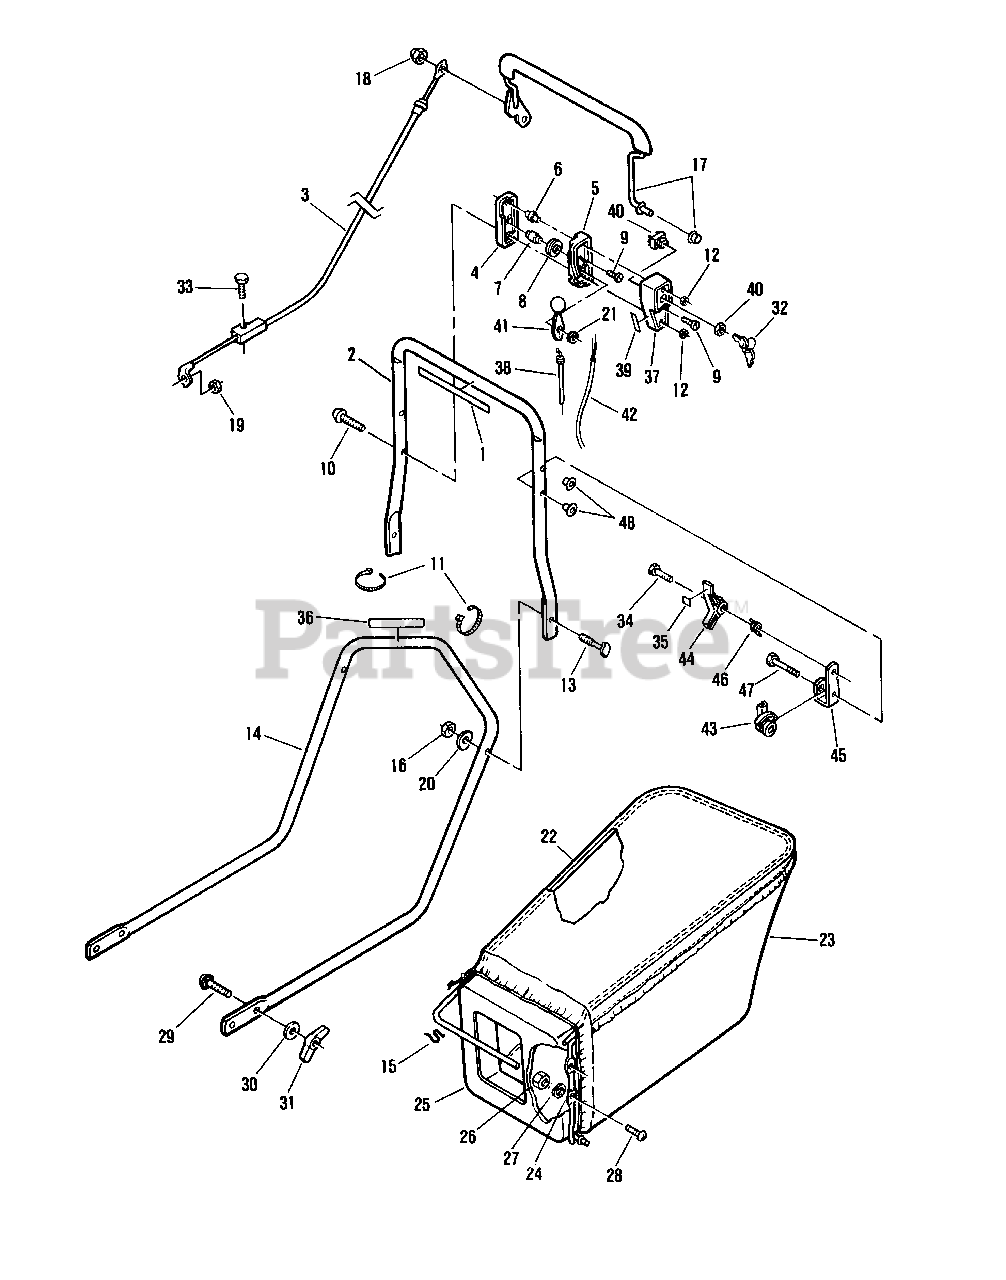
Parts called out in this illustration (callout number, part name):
1	Decal-Engine/Blade Control
2	Handle-Upper
3	Control Cable Assembly
4	Control Case-Outer
5	Control Case-Center
6	Column
7	Pin
8	Pulley
9	Screw
10	Screw
11	Tie Strap
12	Nut-Hex
13	Screw
14	Handle-Lower
15	"S" Clip
16	Nut
17	Control Lever and Nut Assembly
18	Nut-Acorn
19	Nut-Eyebolt and Clutch Arm
20	Washer
21	Washer-Spring
22	Hanger Bag
23	Grass Bag Assembly
24	Latch Bar Assembly
25	Bag Adapter
26	Nut-Bag Adapter
27	Washer
28	Screw-Bar Adapter
29	Bolt-Carriage
30	Washer
31	Wing Nut
32	Keys (2 on a Ring)
33	Screw-Cable to Eng. Mtg. Plate
34	Bolt-Shoulder
35	Decal-Latch Lever
36	Decal-Start Instructions
37	Control Case-Inner
38	Cable-Throttle
39	Decal-Throttle
40	Switch Assembly
41	Lever and Knob Assembly
42	Wire Harness Assembly
43	Cam-Clutch Control
44	Stop-Latch Lever
45	Bracket-Bail Stop
46	Spring-Torsion
47	Bolt-Shoulder
48	Nut-Tube
